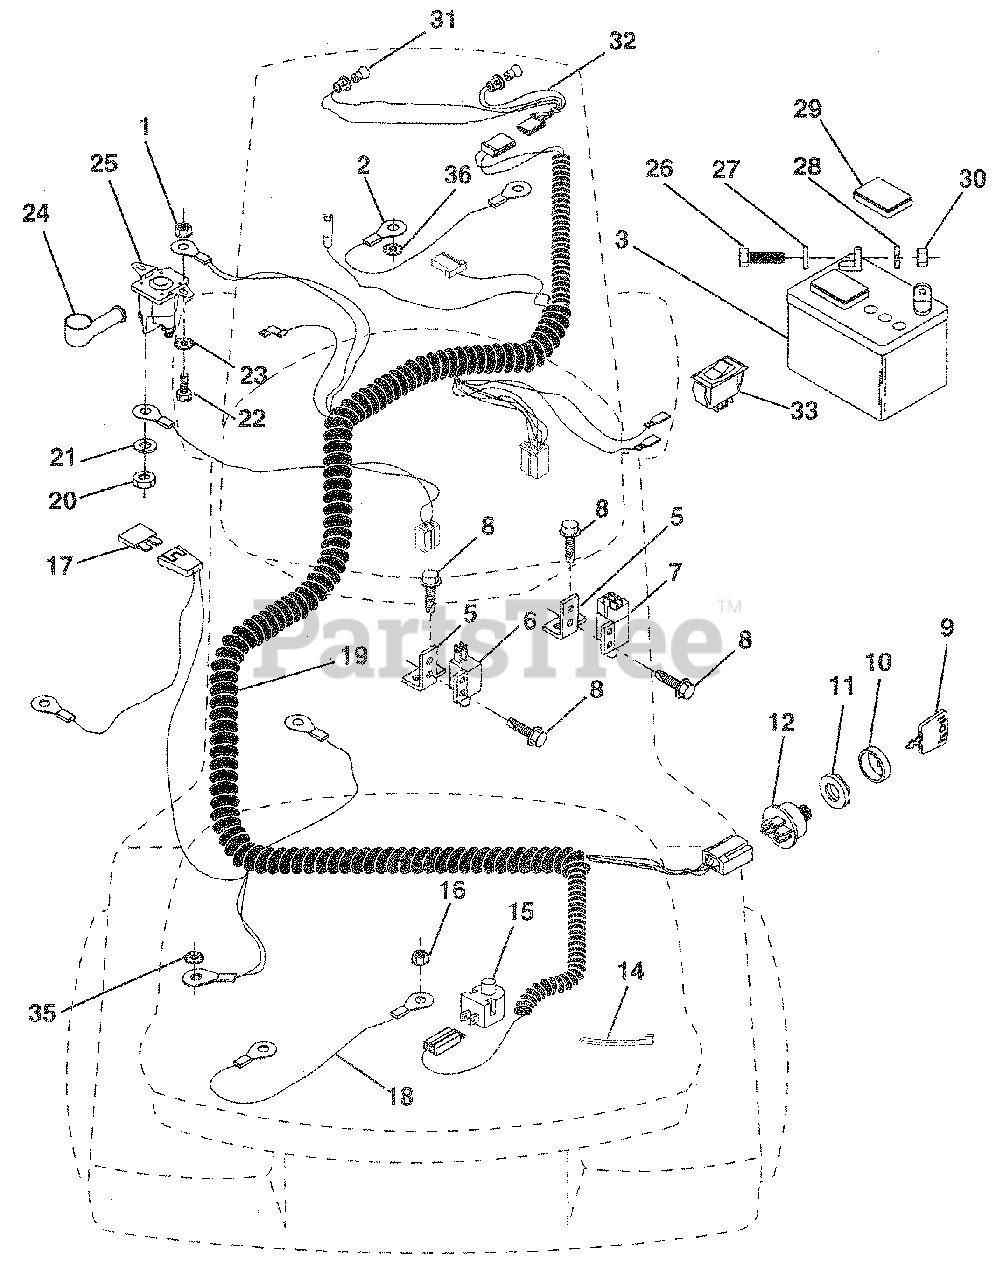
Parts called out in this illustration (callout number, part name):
1	Nut, Hex Keps 1/4-20
2	Assembly, Cable
3	Battery
5	Bracket, Switch
6	Switch, Interlock
7	Switch, Interlock
8	Screw, Hex Hd. Tap #10-24 x 1/2
9	Key, Molded
10	Cover, Key Ignition
11	Nut, Ignition
12	Switch, Ignition
14	Tie, Cable
15	Switch, Plunger
16	Nut, Hex, Keps 5/16-18
18	Assembly, Cable
19	Harness, ignition
20	Nut, Hex Jam 1/4-20
21	Washer, Lock 1/4
22	Bolt, Fin. Hex
23	Washer, Lock Ext. Tooth 1/4
24	Cover, Terminal
25	Solenoid
26	Bolt, Hex Hd. 1/4-20 UNC x 3/4
27	Washer 9/32 x 5/8 x 16
28	Washer, Lock 1/4
29	Cap, Battery
30	Nut, Fin. Hex 1/4 - 20 UNC
31	Bulb, Light
32	Socket, Light Harness
33	Switch, Light
35	Lockwasher Int. Tooth 1/4
